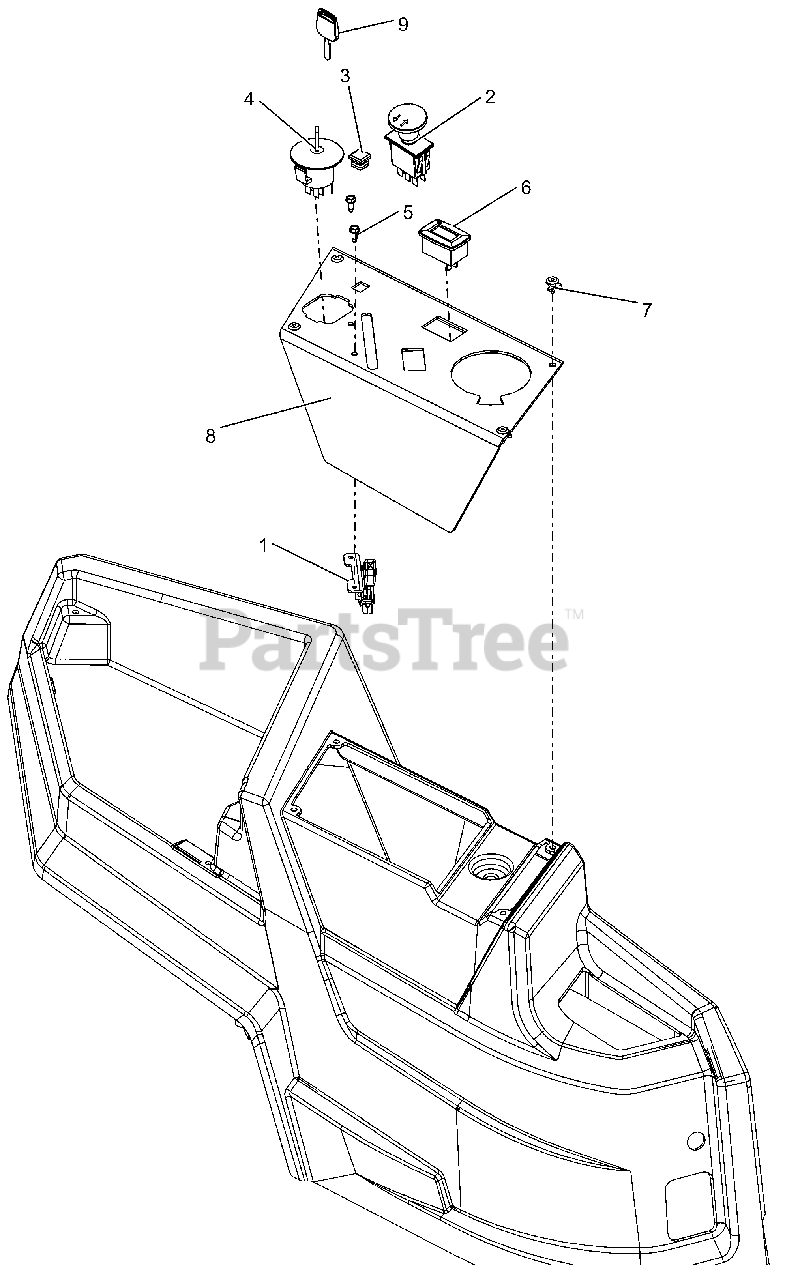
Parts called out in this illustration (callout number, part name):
1	CABLE - THROTTLE CONTROL
2	SWITCH, CLUTCH (YELLOW)
3	PLUG, 5/8" SQ BLACK (14-20GA)
4	KEYSWITCH-IGNITION 4 POS
5	SCR,TAP #10-24X.50 HWH TR ZCC
6	METER, HOUR W/MAINTENANCE
7	RIVET, PLASTIC .195 DIA.
8	PANEL, CONTROL
9	KEY, IGNITION
